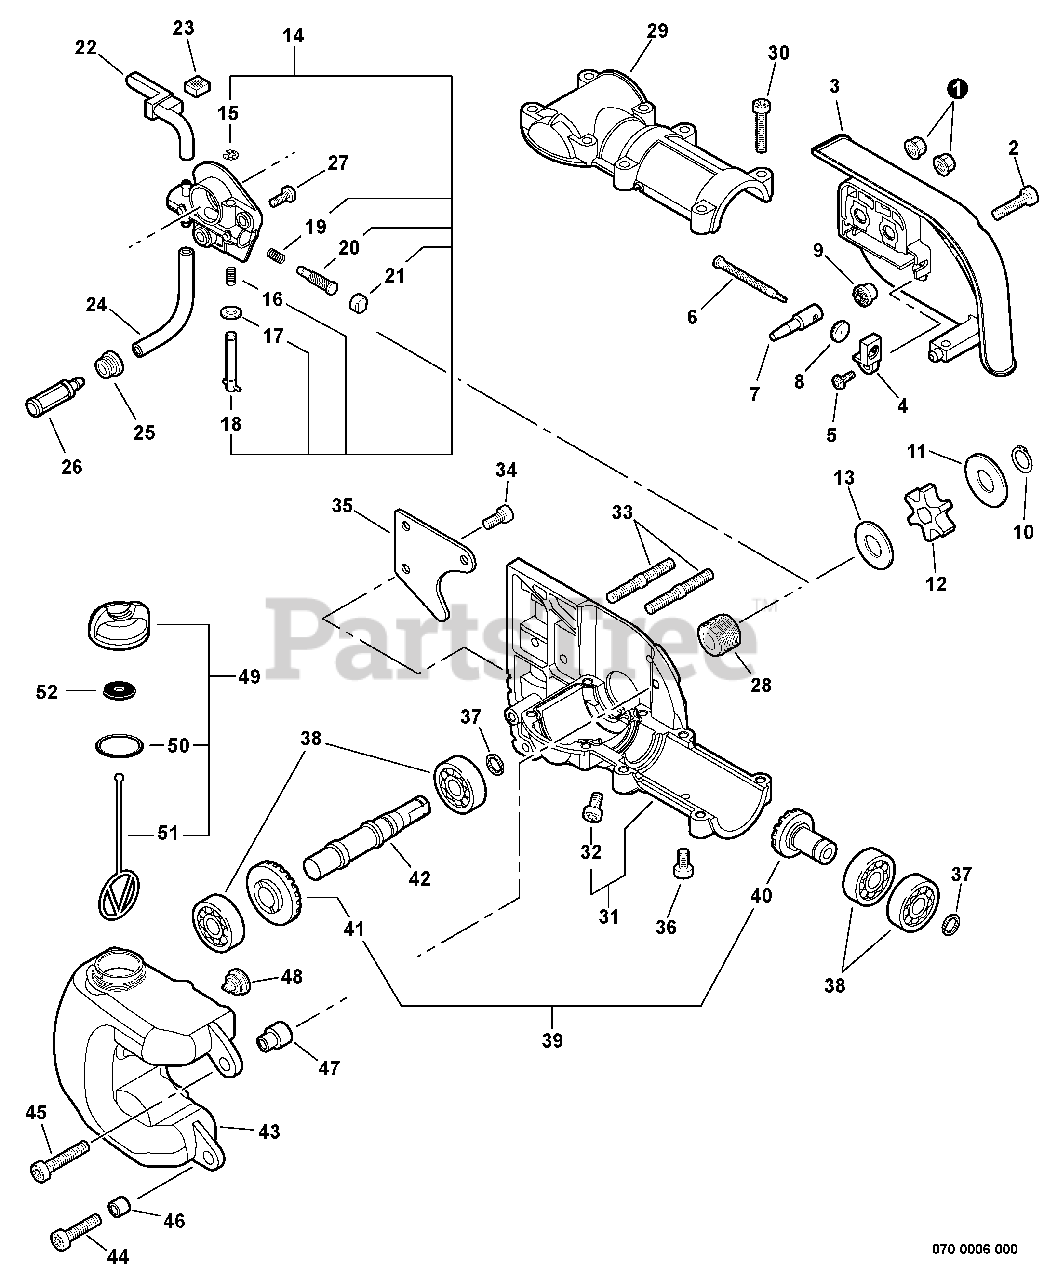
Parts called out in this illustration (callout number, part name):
1	NUT - 6 -- FLANGE
2	SCREW - 5X20
3	GUARD, SPROCKET
4	BRACKET, TENSIONER
5	SCREW - 4X8
6	SCREW, TENSIONER
7	TENSIONER, CHAIN
8	GEAR - BEVEL
9	GEAR - BEVEL
10	RING, RETAINING
11	WASHER - 10
12	SPROCKET, DRIVE
14	AUTO-OILER ASSY
15	RING, RETAINING
18	NEEDLE, ADJUST
20	PLUNGER
21	CAP, OIL PUMP
22	PIPE, OIL OUTLET
23	PAD, FOAM
24	PIPE - 3X6X75 -- BLACK
25	GROMMET
26	FILTER, OIL
27	SCREW - 5X10
28	GEAR - WORM
29	CASE, GEAR - UPPER
30	SCREW - 5X25
31	CASE, GEAR - LOWER
32	SCREW - 5X10
33	STUD, GUIDE BAR
34	SCREW - 5X10
36	SCREW - 5X10
37	RING, RETAINING - 12
38	BEARING, BALL - 6001
39	GEAR SET
40	GEAR - BEVEL
41	GEAR - BEVEL
42	GEAR - SHAFT
43	TANK, OIL
44	SCREW - 5X20
45	SCREW - 5X25
49	CAP ASSY - ORANGE
50	O-RING - 18
51	CONNECTOR, CAP
52	WASHER - RUBBER
